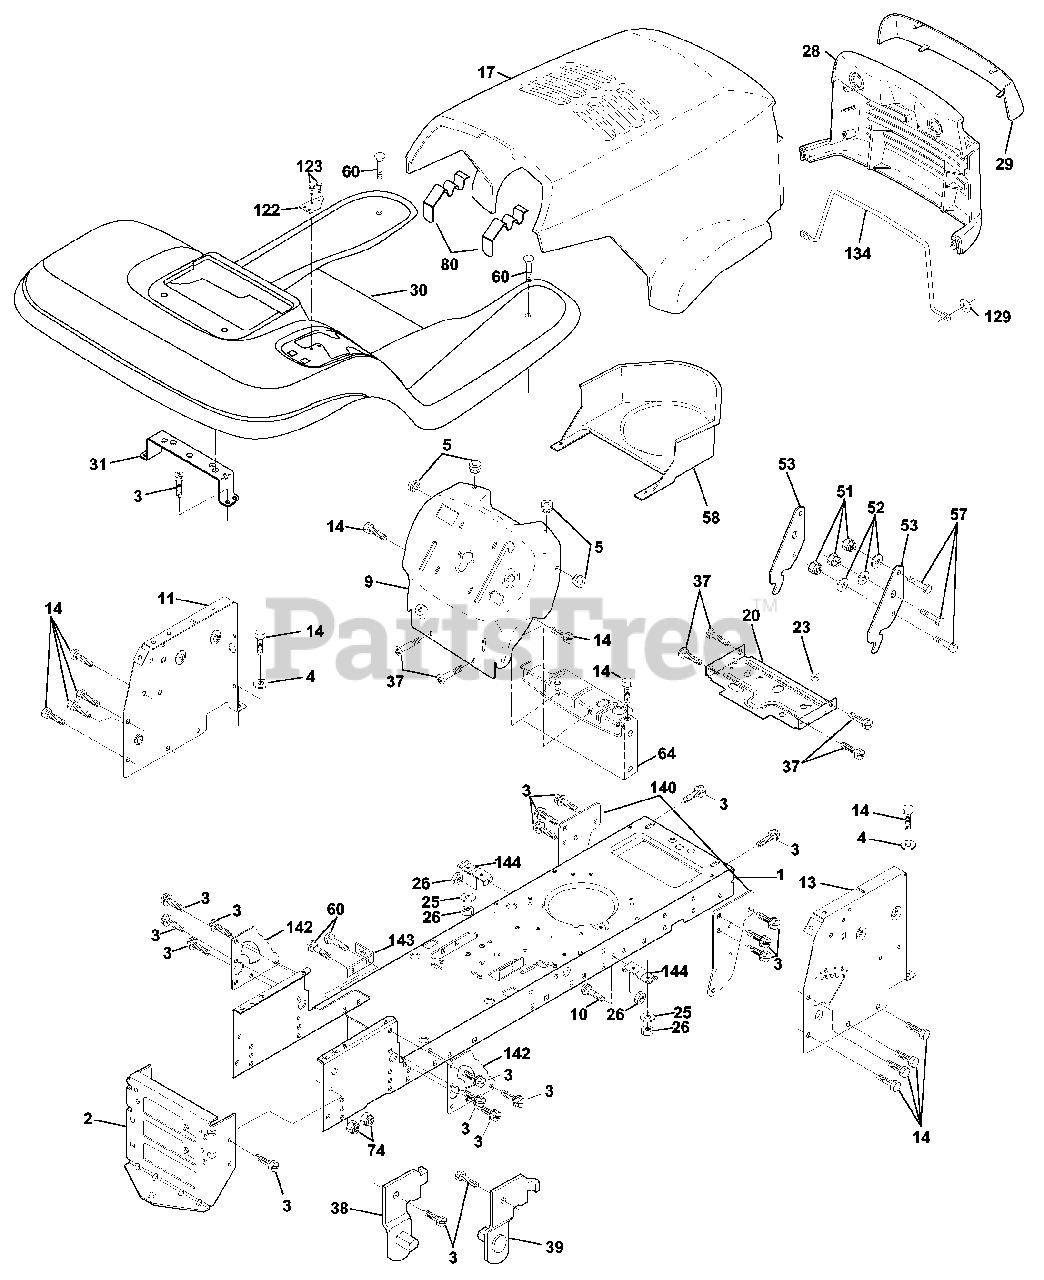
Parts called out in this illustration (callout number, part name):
1	Chassis Weldment
2	Drawbar, Stretch
3	Screw Thdrol 3/8-16x3/4 Ty-tt
4	Washer 13/32 x 3/4 x 16 Ga.
5	Bumper Hood/Dash
9	Dash P/L M, N/AMM N/HM Grey
10	Bolt Carriage 3/8-16 x 1
11	Panel Dash Lh
13	Panel Dash Rh
14	Screw Thdrol 3/8-16x1/2 Ty-tt
17	Hood LT/PL Husqvarna
20	Plate Mtg Battery Fuel Tank Fr
25	Washer 13/32 X 13/16 X 12 Ga
26	Nut Lock Hex W/Ins 3/8-16 Unc
28	Grille LT/PL Husqvarna
29	Lens LT/PL Husqvarna
30	Fender Footrest STLT Pnt
31	Bracket Support Fender
37	Screw Thdrol 6/16-18 x 1/2 TYT
38	Bracket, Asm. Pivot, L.H., Mower Rear
39	Bracket, Asm. Pivot, R.H., Mower Rear
51	Nut Lock Hex W/Ins 1/4-20
52	Washer 9/32 x 7/8 x 16 Ga.
53	Bracket Pnt. Pick off LT/PL Husqvarna
57	Bolt Hex 1/4-20 x 3/4
58	Air Duct Engine P/L
60	Bolt Rdhd Sqnk 3/8-16unc x 3/4
64	Dash Lower STLT
74	Nut Crownlock 3/8-16 UNC
80	Latch Hood Plm Husqvarna
129	Washer 9/32 x 5/8 x 16 Ga.
134	Rod Support Hood LT/PL Husq.
140	Bracket Chassis Front 7 Ga.
142	Plate Reinforcement STLT
143	Bracket Swaybar Chassis
144	Bracket Pnt Footrest STLT
146	Screw Torx Hd Thd 5/16-18 UN-2A
